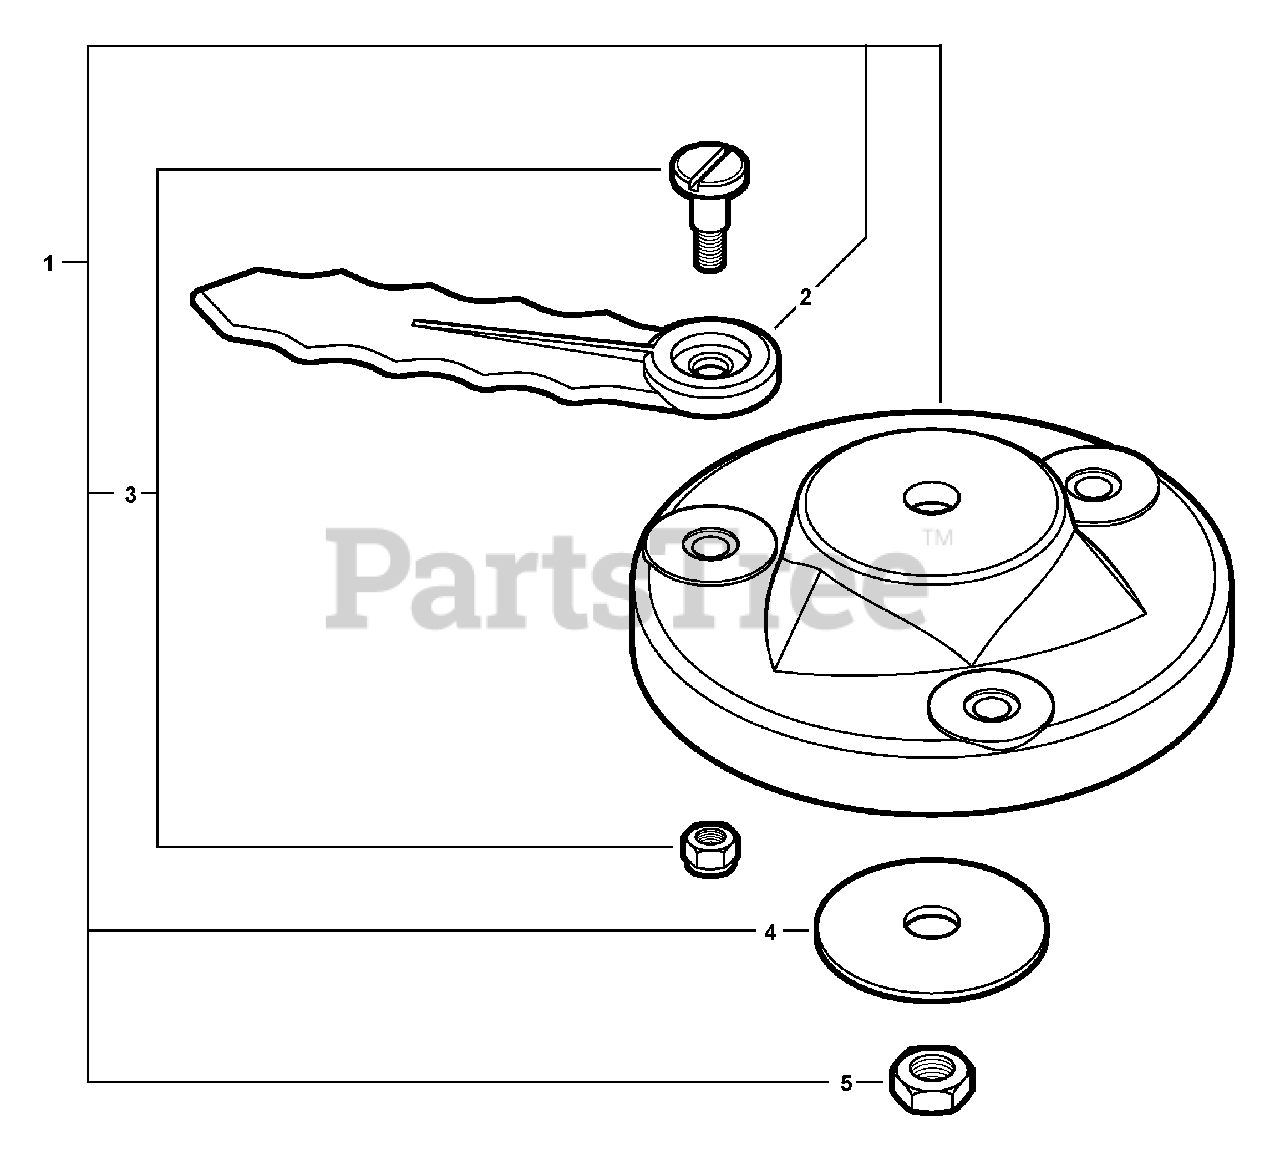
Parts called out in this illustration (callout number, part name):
1	PRO MAXI-CUT HEAD
2	BLADE SET
3	FASTENER SET
4	WASHER, MOUNTING
5	NUT, LOCK
